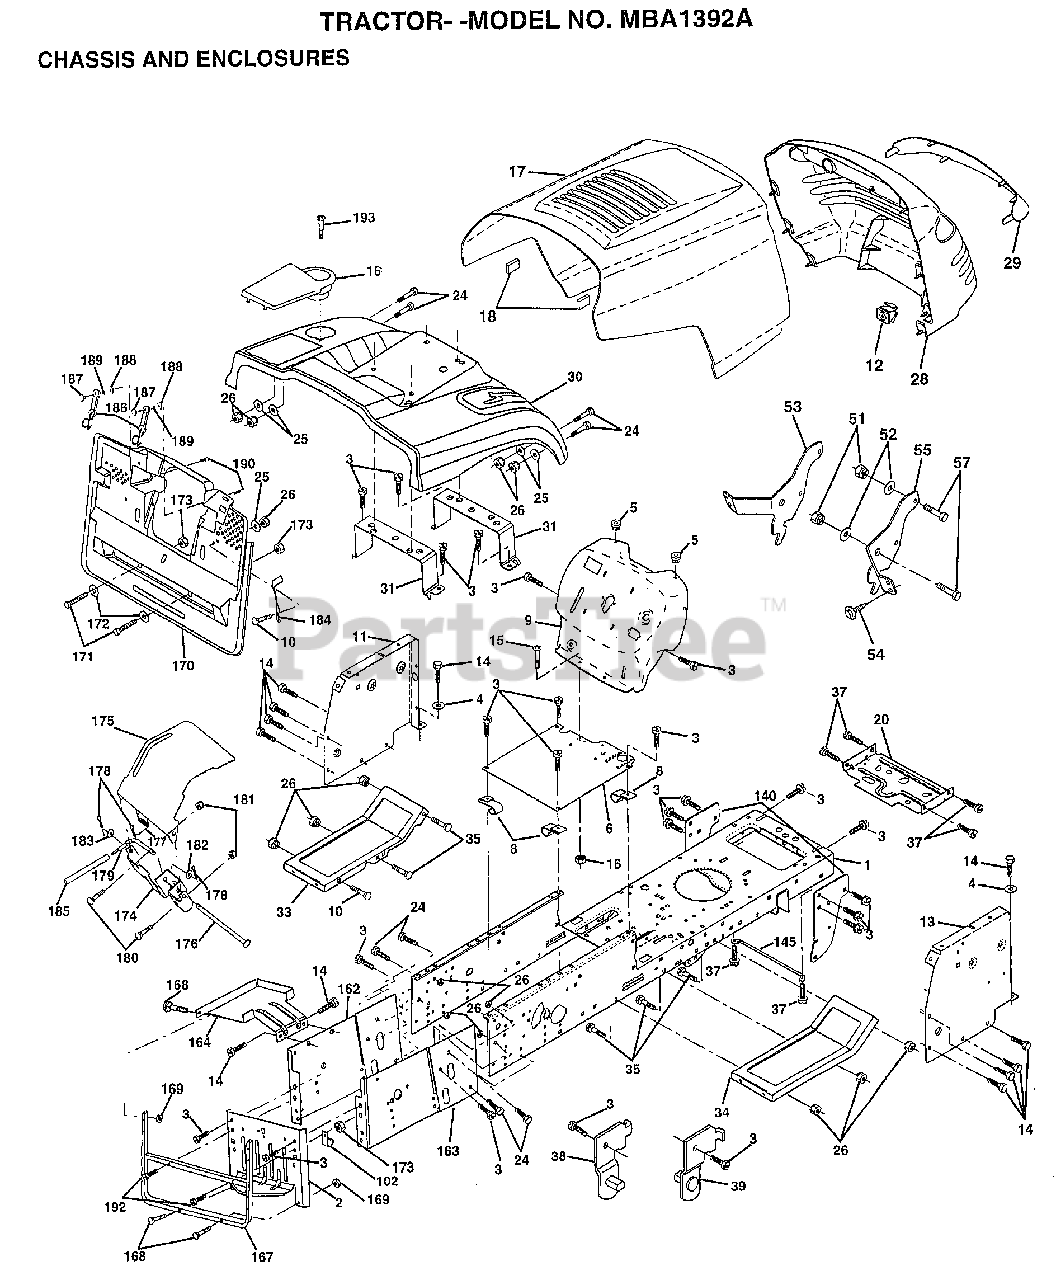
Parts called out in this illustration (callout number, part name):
1	CHASSIS.STAMPING
2	DRAWBAR.CRD
3	SCREW
4	WASHER
5	BUMPER-HOOD/DASH
6	SADDLE
8	"CLIP,INSULATOR"
9	DASH.SILKSCREEN
11	"PANEL-DASH,LH"
12	CLIP.TINNERMAN
14	SCREW LT
15	SCREW
17	HOOD.PNT.W/TRIM
20	"PLATE-MTG,BATT/FU"
24	BOLT
25	WASHER
26	NUT
28	GRILLE
29	LENS.GRILLE
31	BRKT.SUPT.FENDER.CRD
33	FOOTREST.LH.YT/GT
34	FOOTREST.RH.LT/YT
35	BOLT
37	SCREW LT
38	BRACKET ASM LH
39	BRACKET ASM RH
51	NUT
52	WASHER
53	BRACKET.GRILLE.LH
54	SCREW.HEX.WS.HD
55	BRACKET.GRILLE.RH
102	CLIP T
140	BRKT SUSPENSION
145	"ROD POVOT,CHASSIS"
162	BRKT.EXT.CHASSIS.LH.CRD
163	BRKT.EXT.CHASSIS.RH.CRD
164	SUPPORT.BATTERY.CRD
165	COVER.BATTERY.CRD.BLACK.LT
170	COVER.BACKPLATE.BLACK
171	BOLT.HEX.3/8-16X2-1/2
173	NUT
174	BRKT.SWITCH.FBI.CRD
175	GRUARD.DOOR.REAR.CRD
176	HINGE PIN
177	SPRING.COVER.LH
179	ROD.PIVOT.FBI.CRD
182	WASHER.385X.625
183	WASHER
184	BRKT.ACTUATOR.BAG.CRD
185	TUBE.LEVER.SWCH.FBI.CRD
186	LATCH ASSY.BAGGER
187	WELDNUT
188	WASHER #10
189	LOCKWASHER
190	SCREW
193	SCREW LT
